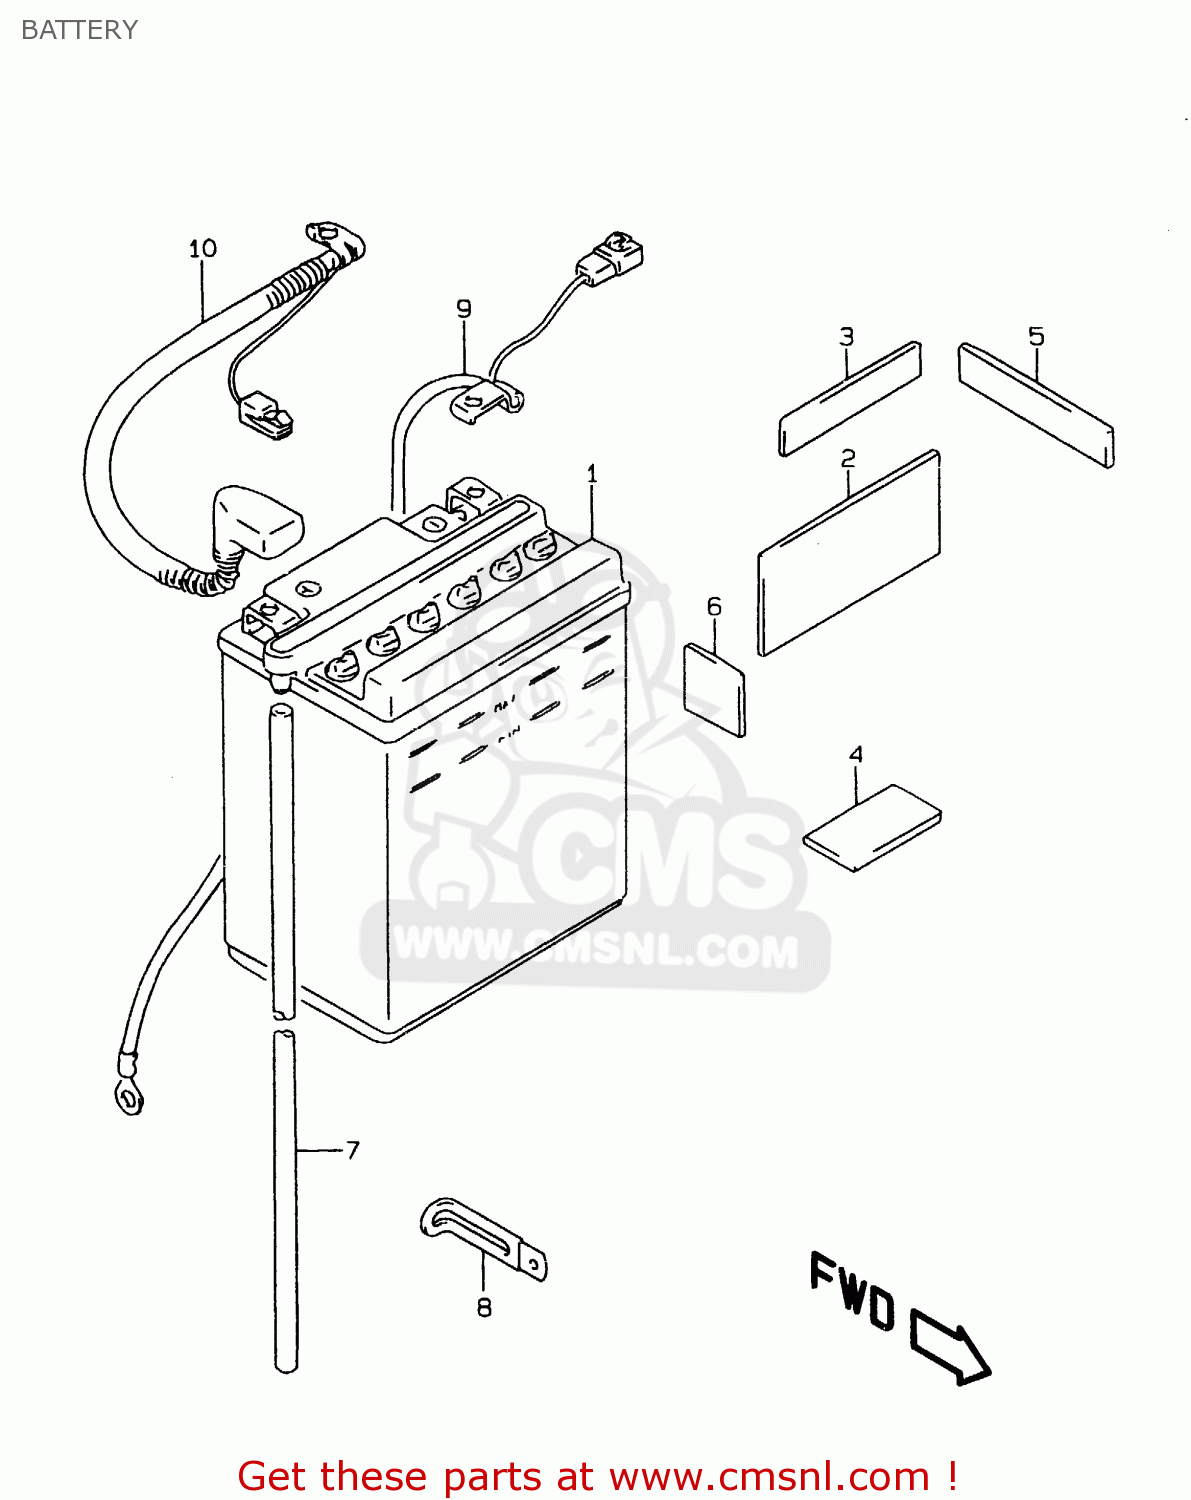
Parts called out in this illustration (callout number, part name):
1	BATTERY(YB14L-B2,12V14.7AH)
2	PROTECTOR(170X95X3.0)
3	PROTECTOR(170X95X3.0)
4	PROTECTOR(170X95X3.0)
5	PROTECTOR(80X80X2)
6	PROTECTOR(50X50X5)
7	HOSE,BATTERY EXHAUST(L:780)
8	CLAMP(L:65)
9	WIRE,BATTERY MINUS
10	WIRE,BATTERY PLUS LEAD
